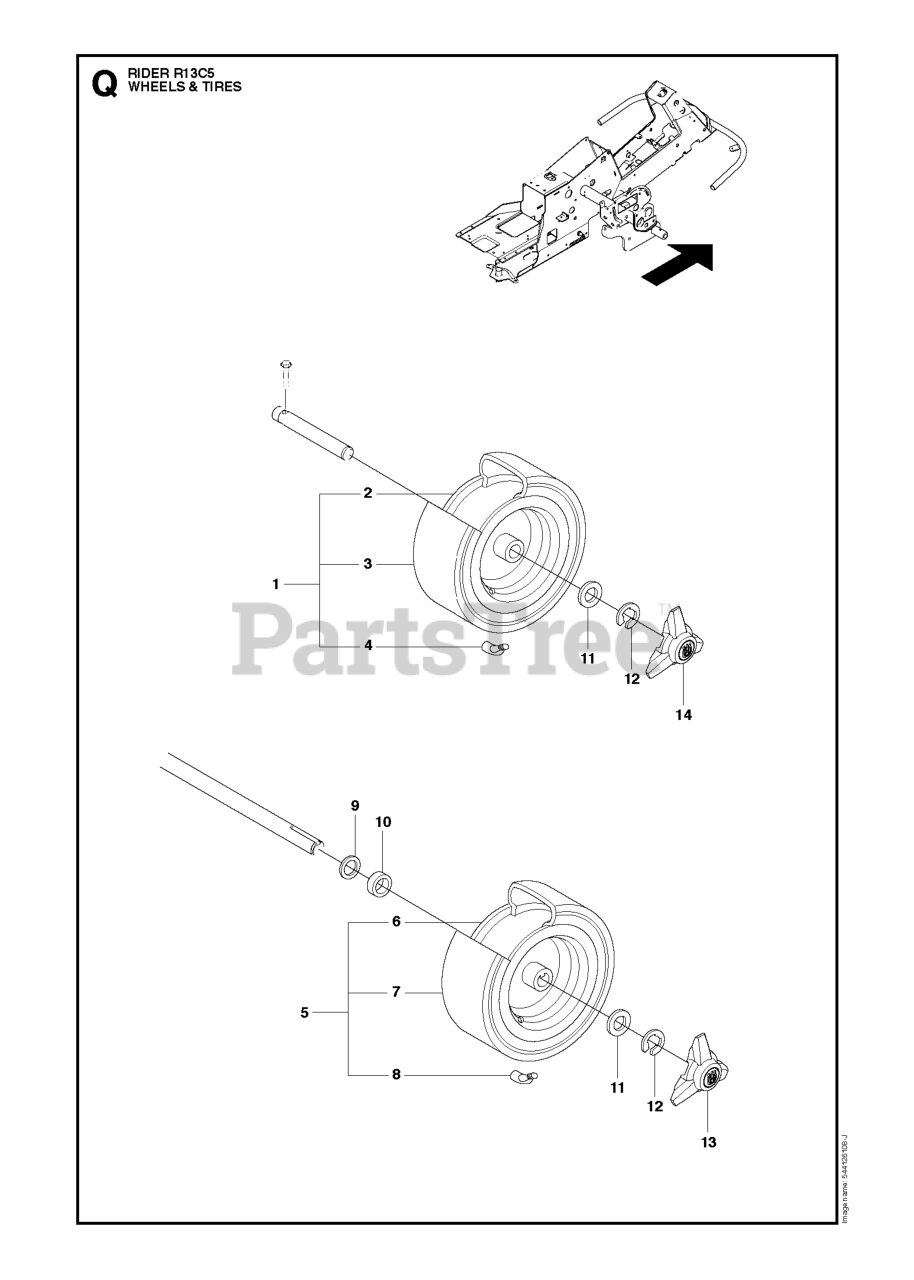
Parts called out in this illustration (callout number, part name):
5	WHEEL
6	RP RIM
12	RETAINING RING
